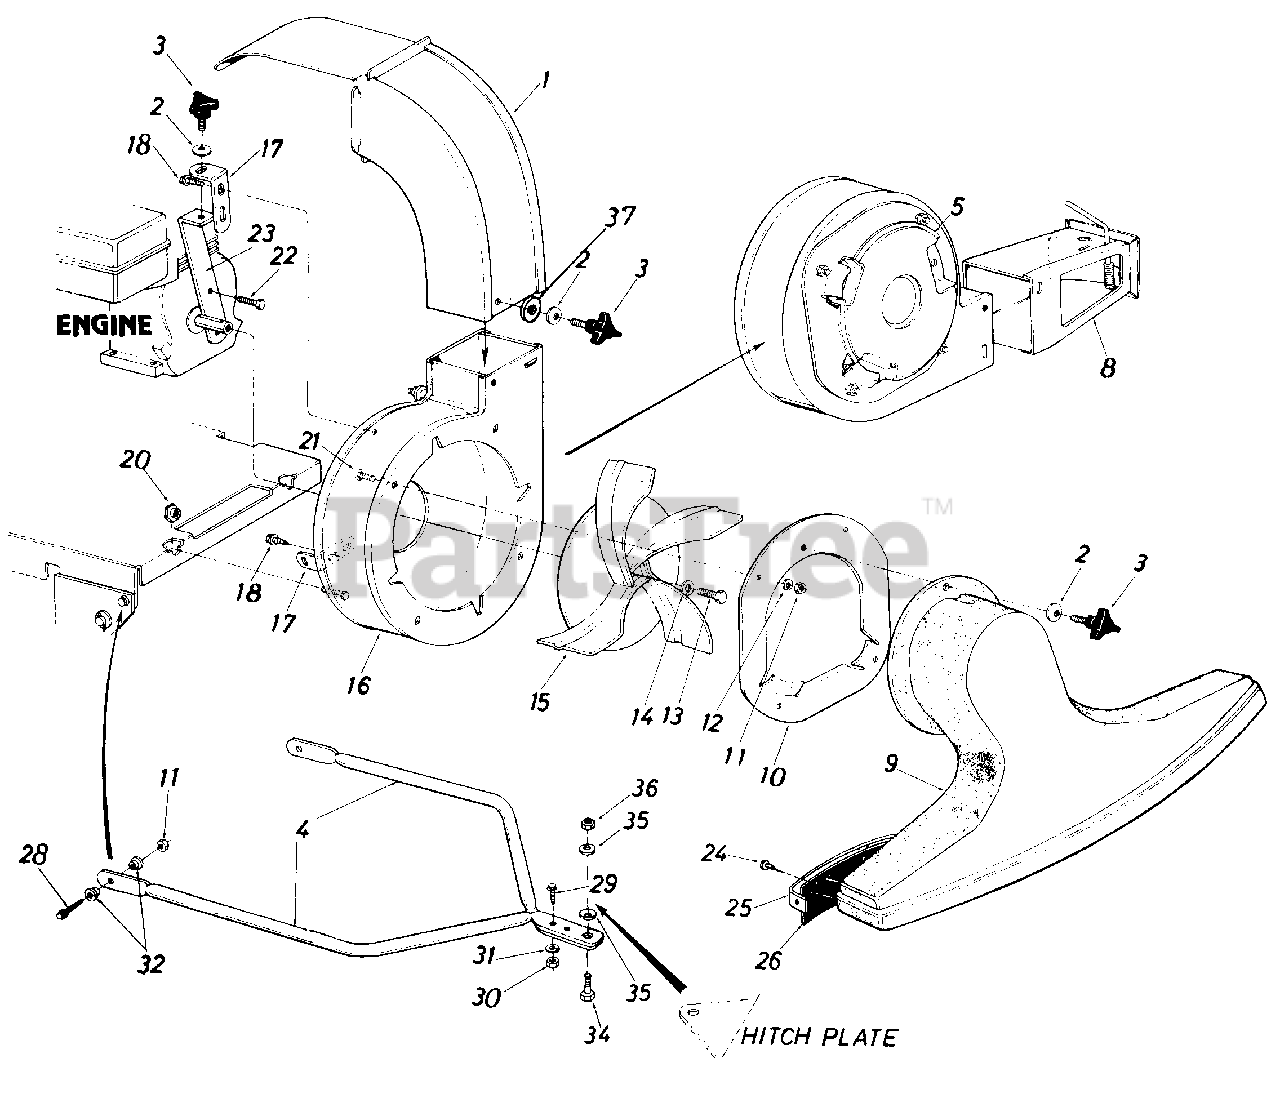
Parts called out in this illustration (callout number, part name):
3	Arm Thumb Scr. 5/16-18 x .75" Lg.
10	Nozzle Plate Ass'y.
11	Hex Nut 5/16-18 Thd.*
12	L.-Wash. 5/16" I.D.
13	Hex Bolt 3/8-24 x 1.25" Lg.*
14	L.-Wash. 3/8" I.D. H.D.
15	Air Vane Plate Ass'y.
16	Blower Housing Complete
20	Hex Shoulder Nut .50 I.D.
21	Carriage Bolt 5/16-18 x .62" Lg.*
22	Hex Locking Bolt 5/16-24 x .75" Lg.
28	Hex Bolt 5/16-18 x 1.00" Lg.*
29	Truss Mach. Scr. 1/4-20 x .75" Lg.*
30	Hex Nut 1/4-20 Thd.*
31	L.-Wash. 1/4" I.D.*
32	Shoulder Spacer
34	Shld. Bolt .496 Dia.
35	Belleville Wash. .39 I.D. x 1.12 O.D.
36	Hex Jam L-Nut 3/8-16 Thd.
37	Fl-Wash. 5/16" I.D.
